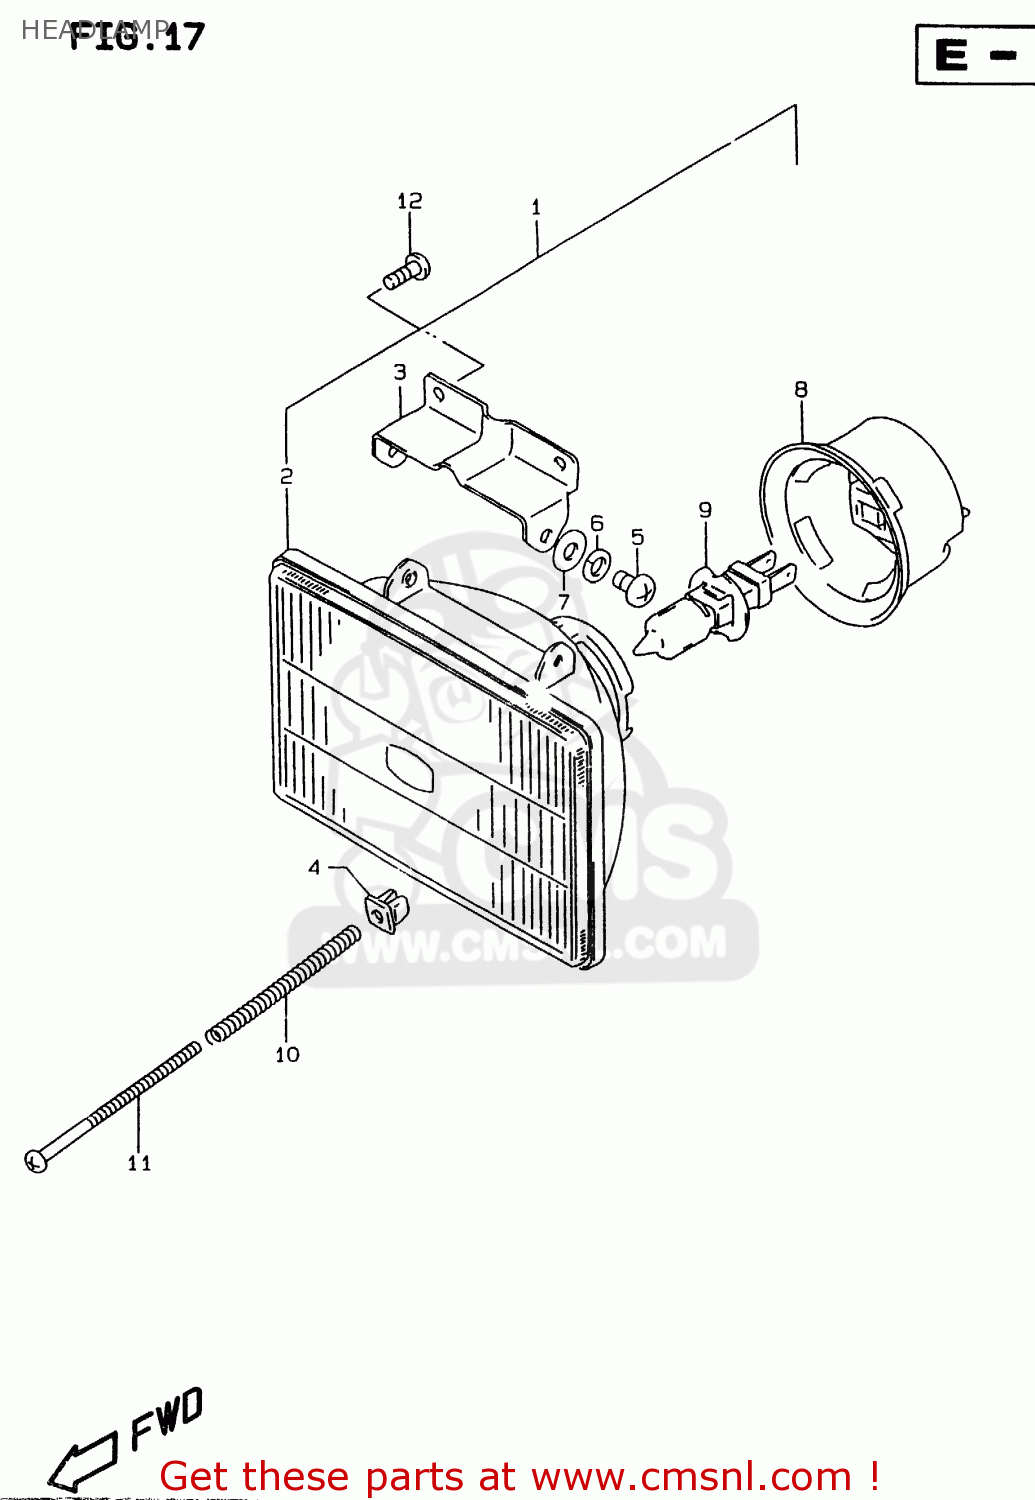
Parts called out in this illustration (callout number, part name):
1	HEADLAMP ASSY
2	UNIT,LAMP
3	BRACKET,LAMP
4	NUT,ADJUSTING
5	SCREW
6	WASHER,LOCK
7	WASHER
8	COVER,SOCKET
9	BULB(12V55W)
10	SPRING,HEAD LAMP ADJUSTER
11	SCREW(4X45)
12	SCREW
